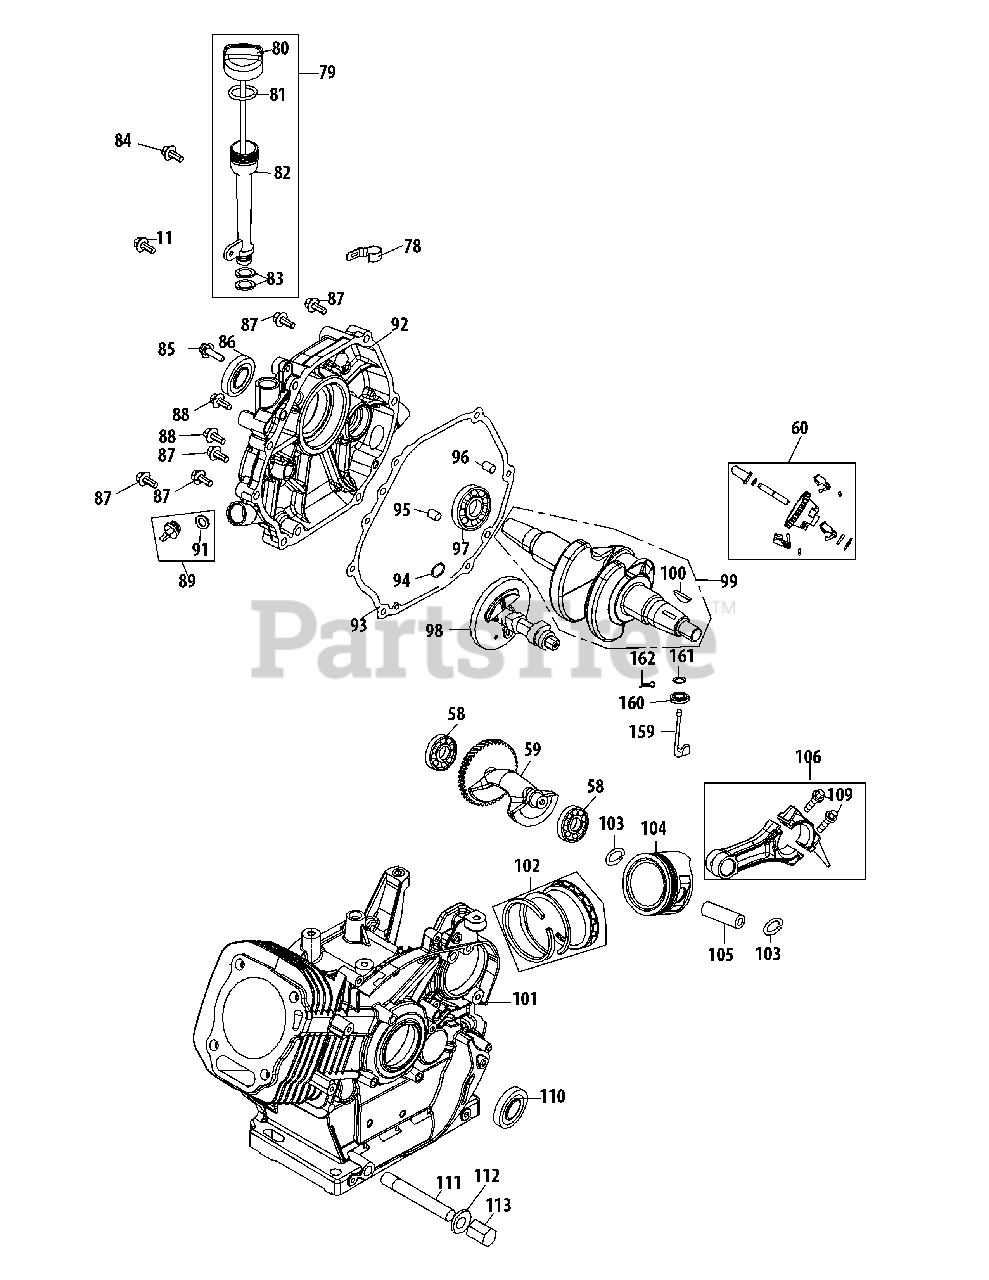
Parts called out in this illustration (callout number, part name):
11	BOLT M6×8
58	RADIAL BALL BEARING, 6202-P6
59	BALANCEABLE SHAFT ASSY.
60	GOVERNOR GEAR
78	DIPSTICK CLAMP
79	DIPSTICK ASSEMBLY
80	DIPSTICK
81	DIPSTICK O-RING
82	OIL FILL TUBE
83	OIL FILL TUBE O-RING
84	BOLT M6×8
85	BOLT M8×45
86	OIL SEAL, 35×52×7
87	BOLT M8×38
88	BOLT M8×35
89	OIL FILLER PLUG COMP
91	O-RING 16×3
92	CRANKCASE COVER
93	CRANKCASE COVER GASKET
94	WASHER 16×24×0.5
95	DOWEL PIN 9×12
96	DOWEL PIN 7×14
97	BEARING, 6207-P6
98	CAMSHAFT ASSEMBLY
99	CRANKSHAFT ASSEMBLY
100	WOODRUFF KEY
101	CRANKCASE COMP.
102	PISTON RING SET
103	PISTON PIN SNAP RING
105	PISTON PIN
106	CONNECTING ROD ASSEMBLY
109	CONNECTING ROD BOLT
110	OIL SEAL 35×52×7
111	OIL DRAIN PIPE
112	WASHER 10×16×1.5
113	OIL DRAIN PLUG
159	GOVERNOR ARM SHAFT
160	GOVERNOR SEAL
161	WASHER 8×20×0.8
162	COTTER PIN
